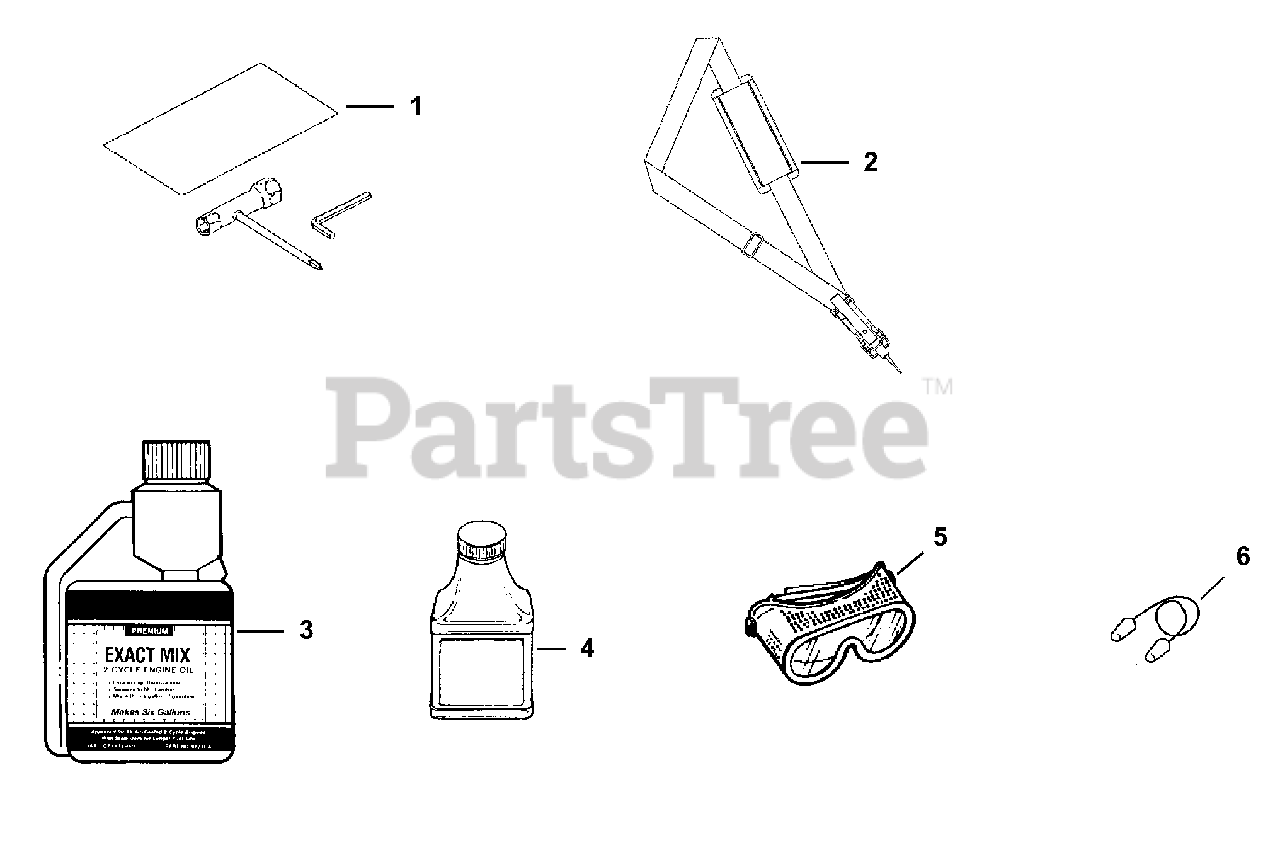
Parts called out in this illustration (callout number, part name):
1	TOOL KIT
3	EXACT MIX(TM) (16 oz.)
4	EXACT MIX(TM) (2.6 oz.)
6	EAR PLUGS
7	DECAL KIT
